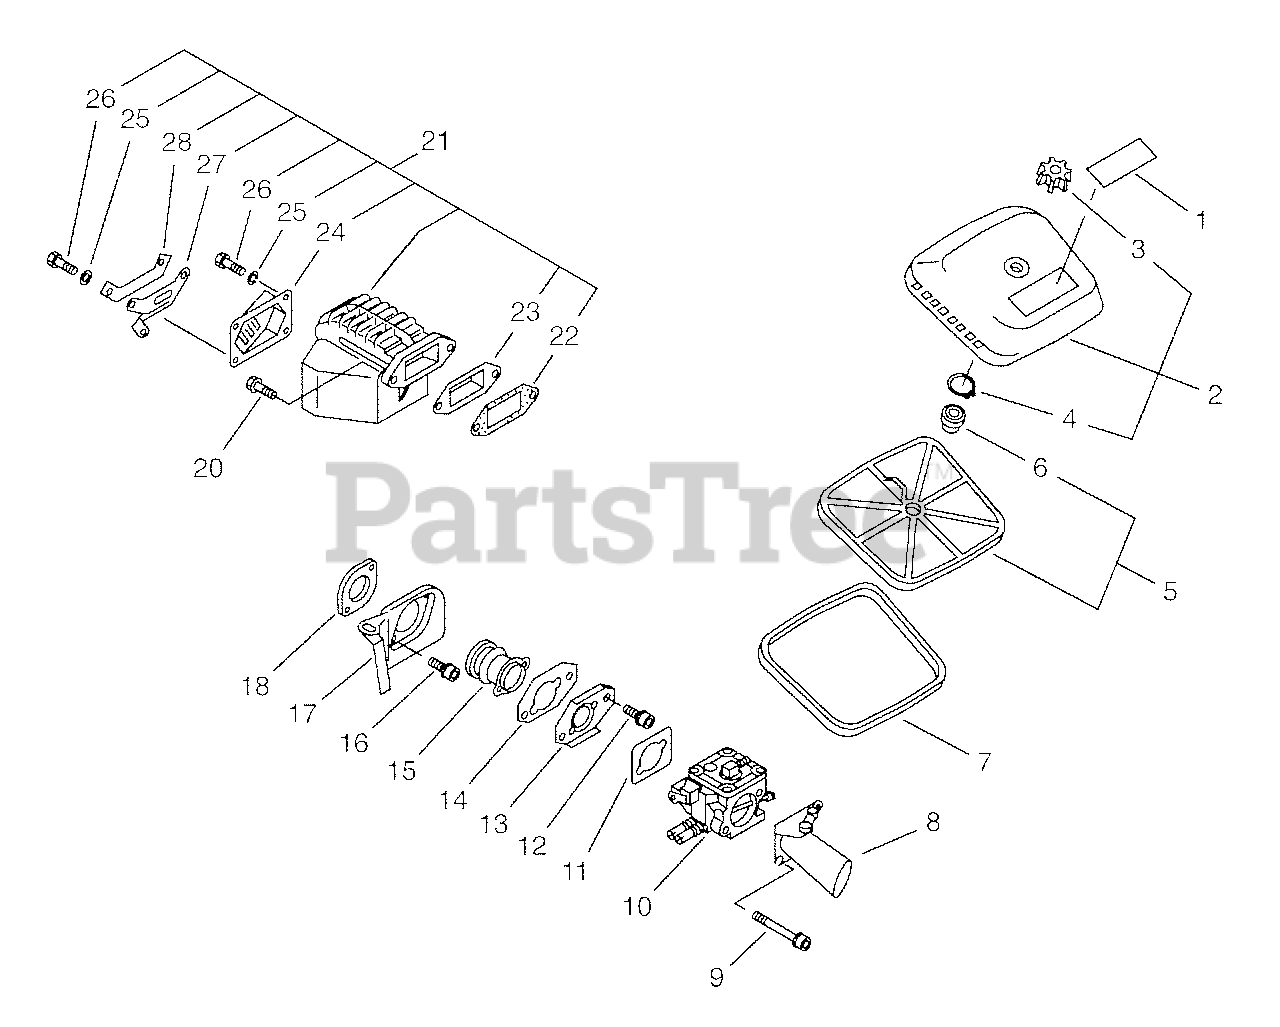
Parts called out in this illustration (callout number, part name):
1	LABEL - MODEL
2	AIR FILTER COVER ASSY
4	RING, RETAINING - 11
5	FILTER, AIR
6	GASKET, AIR CLEANER
8	ADAPTOR, INTAKE
9	SCREW - 5X50
10	CARBURETOR
12	SCREW - 5X14
13	ADAPTOR, CARBURETOR
14	SEAL, DUST
15	BELLOWS, INTAKE
16	SCREW - 5X20
18	RETAINER
20	SCREW - 6X25
21	MUFFLER ASSY
22	GASKET, EXHAUST
23	DIFFUSER, EXHAUST
24	PLATE, EXHAUST
25	WASHER - 5
26	SCREW - 5X15
28	WASHER
